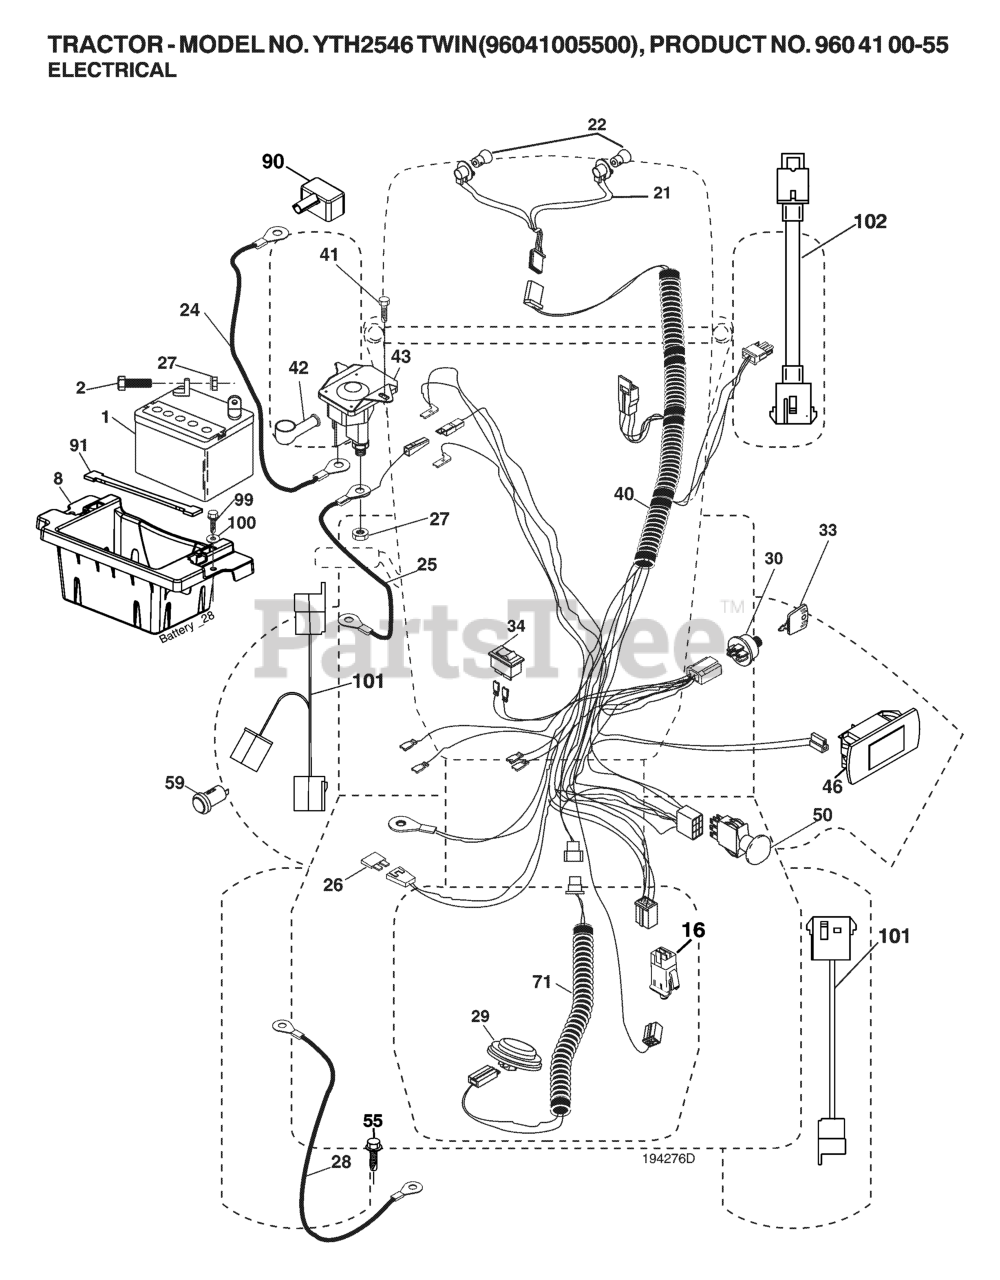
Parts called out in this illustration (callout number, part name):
1	BATTERY 12V .35 AMP
2	BOLT.HEX.1/4.X.3/4.DICHROMATE
8	BOX.BATTERY.MOUNT.FRONT.LT
16	SWITCH INTERLOOK PUSH-IN
21	HARNESS ASSY LIGHT
24	CABLE.BATT.POS.WIRE.TG.DA SOL
25	CABLE.START.RED.17.5".
26	FUSE 20AMP
27	NUT
28	CABLE GROUND 6 GA 21" 90T BLK
29	SWITCH.SEAT.DELTA.OPC.
30	SWITCH.IGN.DELTA.W.LGH.ROS
33	KEY MLD GEN DELTA
40	HARNESS.IGN.ELE.RELAY.TEX.46"
41	SCREW
42	TERMINAL COVER
43	SOLENOID.W/BRASS.PLUNGER
46	RP.GUAGE.SRVCMNDR.HRMTR.
50	RP.PTO.SWITCH.8 TERMINAL.BLACK
55	SCREW 5/16"
59	OUTLET.12-VOLT
71	HARNESS-CHASSIS SUB
90	COVER.TERMINAL.BATTERY
91	STRAP.BATTERY.MOUNT.FRONT(2 2)
99	SCREW HEXWSHR 1/4-20X3/4
101	PIGTAIL.MATNLK.NEW.HAR
102	HARNESS PIGTAIL PCH TEX ROS
103	HARNESS PIGTAIL 12V OUTLET
